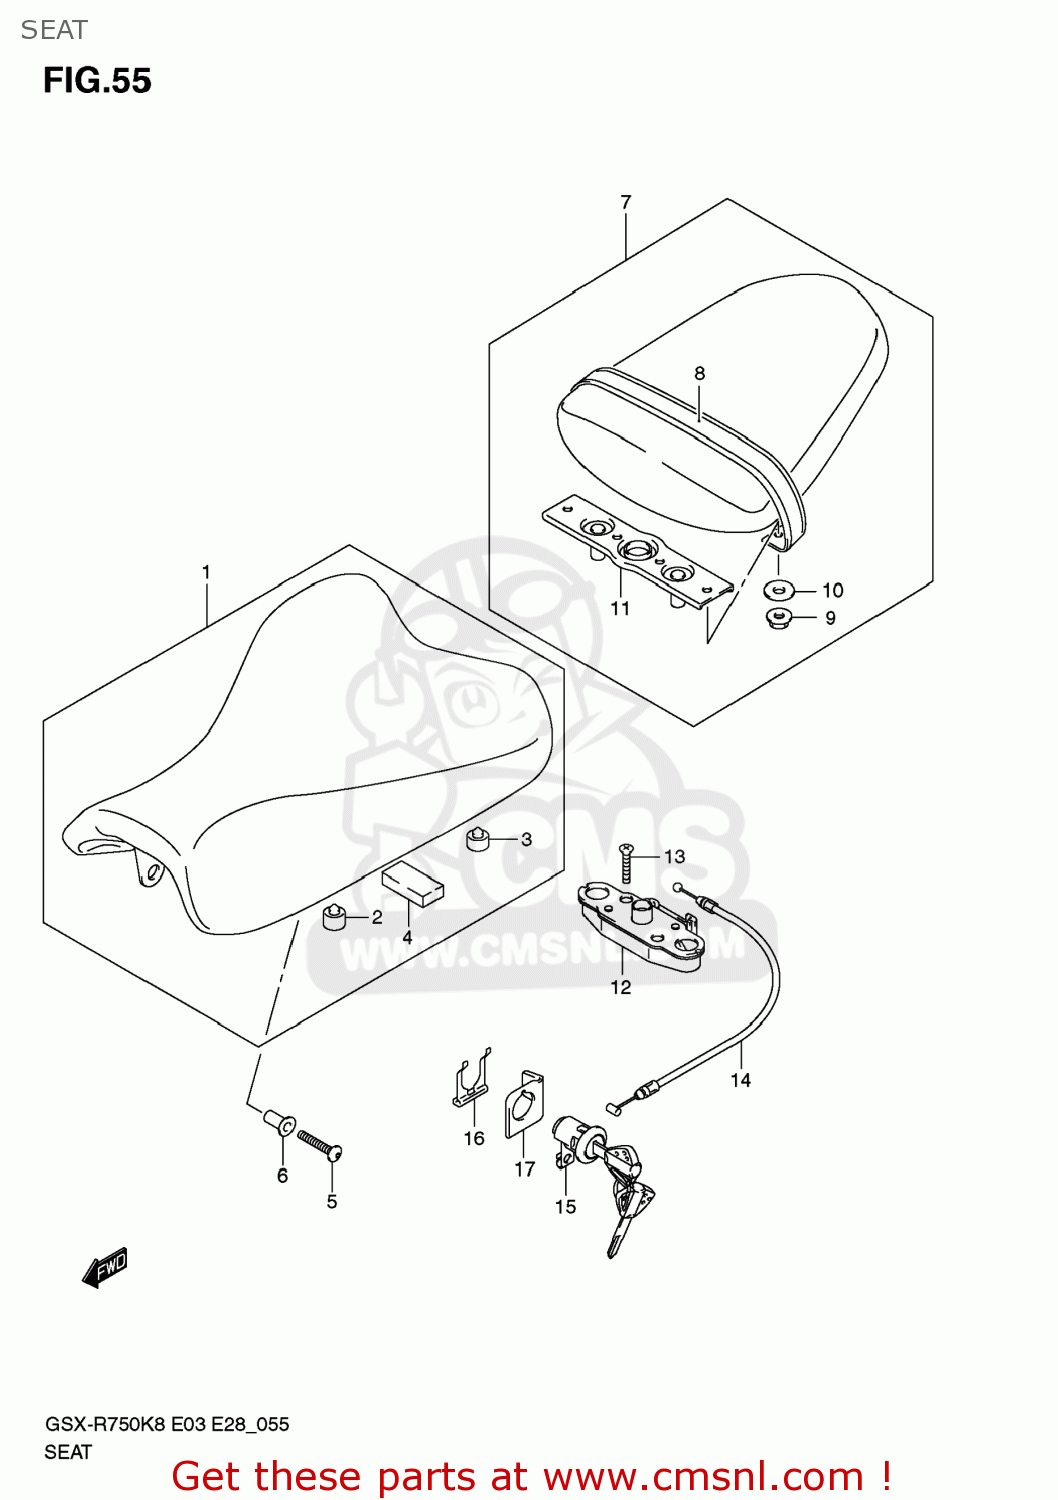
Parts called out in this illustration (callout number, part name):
1	SEAT ASSY
2	CUSHION
3	CUSHION
4	CUSHION
5	SCREW(6X30)
6	SPACER(6.5X9X19.4)
7	SEAT ASSY,PILLION
8	BAND ASSY(BLACK)
9	NUT
10	WASHER(6.5X20X1.6)
11	STRIKER
12	BRACKET,SEAT SUPPORT,RIGHT
13	SCREW
14	CABLE,SEAT LOCK
15	LOCK SET,SEAT
16	PLATE,SEAT LOCK ASSY
17	GUIDE,SEAT LOCK CABLE
